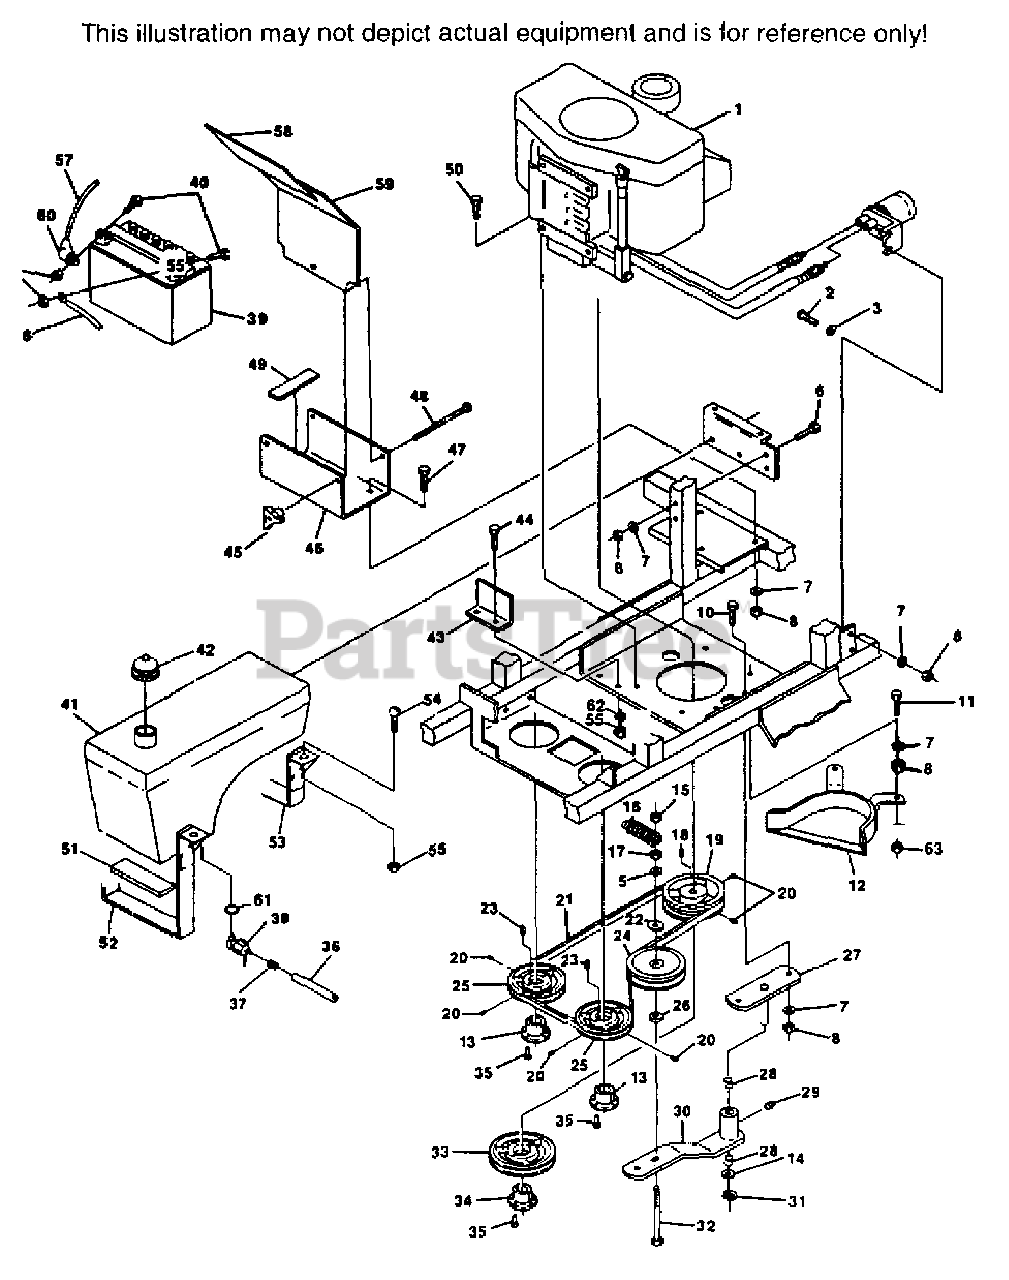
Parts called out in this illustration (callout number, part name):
1	ENGINE, 20 HP KOHLER
12	BELT GUIDE
13	TAPERED HUB, 3/4" BORE
16	SPRING, IDLER ARM
18	KEY, 1/4 X 1/4 X 2-1/2"
19	PULLEY, ENGINE - PUMP DRIVE
20	SETSCREW, 5/16-18 X 3/8 HEX SOCKET HEAD
21	BELT, PUMP DRIVE
23	KEY, WOODRUFF #61
24	PULLEY, IDLER PUMP DRIVE
25	PULLEY, PUMP SHAFT
26	FLAT WASHER, 3/8 X 12 GA.
27	IDLER PIVOT
28	BUSHING
29	GREASE FITTING
30	IDLER ARM(INCLUDES BUSHINGS & GREASE FTG.)
31	RETAINING RING, 3/4 EXTERNAL "E"
32	HEX HEAD BOLT, 3/8-16 X 3-1/2 FULL THREAD
33	PULLEY, ENGINE - CUTTER DRIVE
34	HUB, PULLEY
36	FUEL HOSE, 10" LONG
37	CLAMP, FUEL HOSE
38	FUEL SHUT OFF VALVE
39	BATTERY
41	FUEL TANK
42	FUEL TANK CAP W/GUAGE
43	HEAT DEFLECTOR
45	WINGNUT, 1/4-20
49	PAD, BATTERY SUPPORT
51	RUBBER PADS, GAS TANK
52	FUEL TANK STRAP, LONG
53	FUEL TANK STRAP
57	BATTERY CABLE, RED 30-3/4"
58	BATTERY COVER PAD
59	BATTERY COVER
60	RUBBER BOOT
